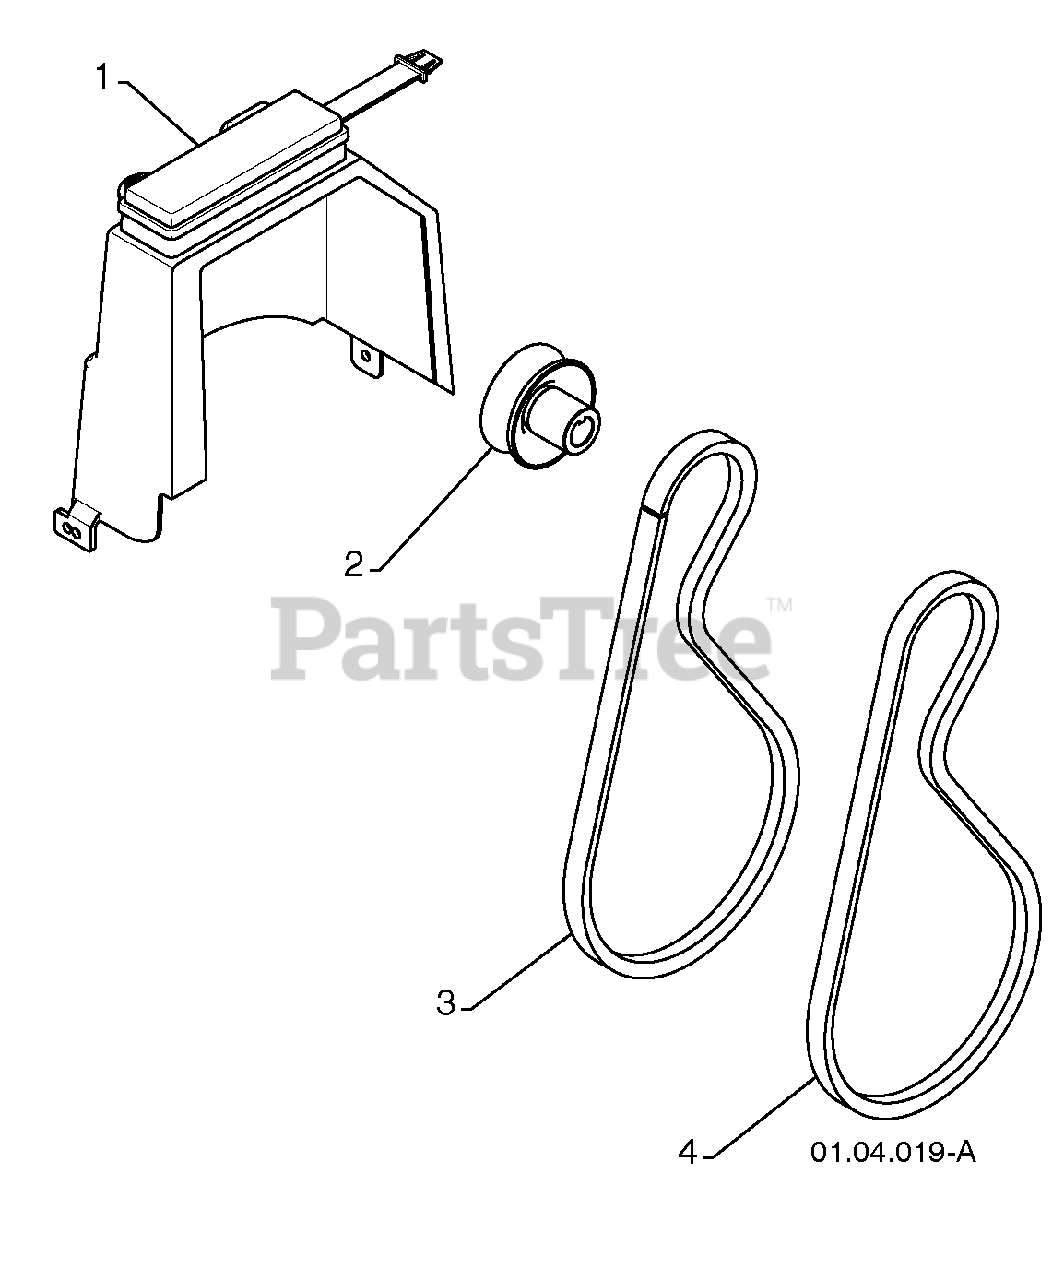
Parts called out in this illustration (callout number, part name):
1	BELT COVER
2	IMPELLER PULLEY
3	TRACTION BELT
4	IMPELLER BELT
